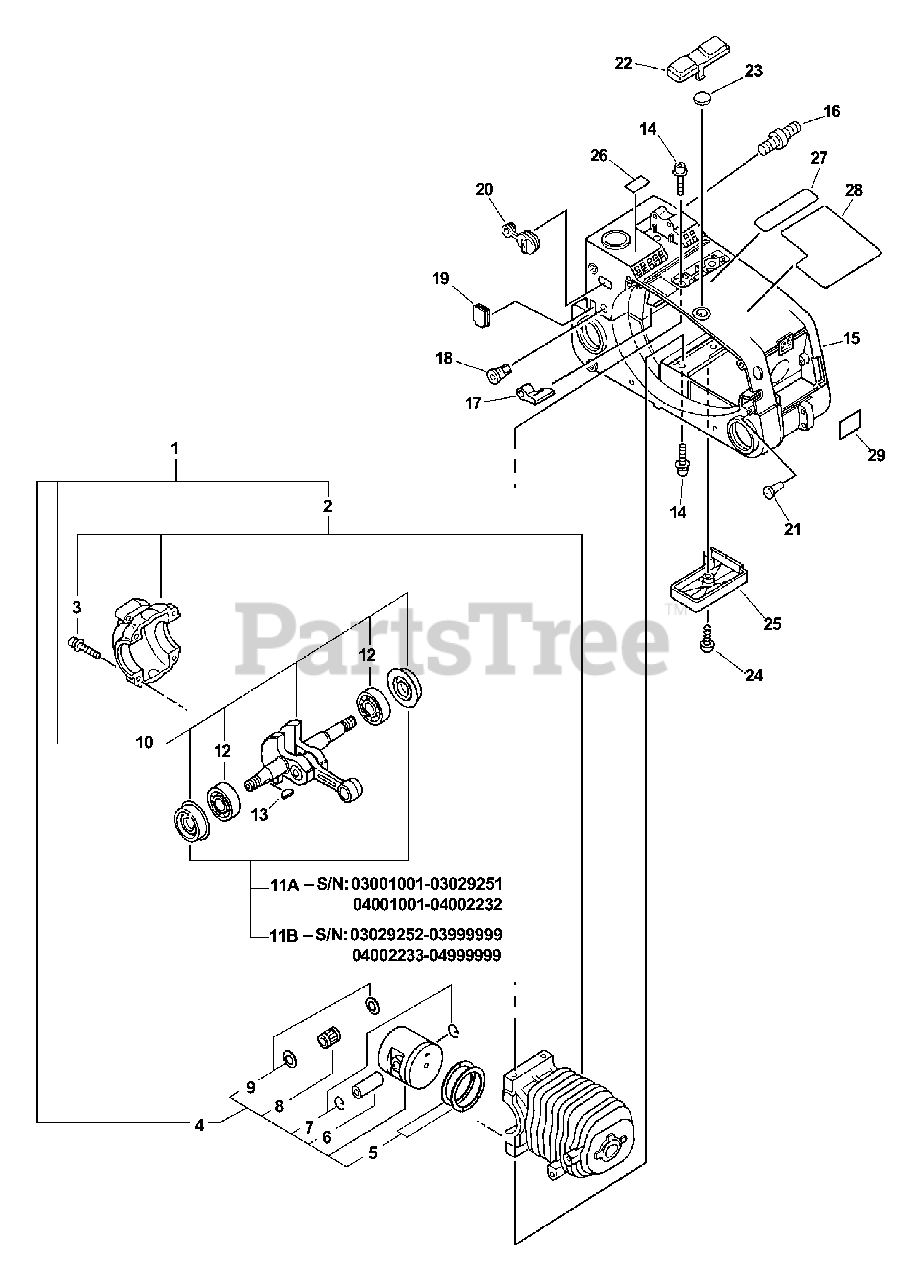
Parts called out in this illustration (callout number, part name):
1	SHORT BLOCK
2	CRANKCASE SET
3	SCREW 5×25
4	PISTON KIT
5	RING, PISTON
6	PIN, PISTON
7	RING, SNAP
8	BEARING, NEEDLE 8
9	WASHER, THRUST
10	CRANKSHAFT ASSY
11A	SEAL, OIL
11B	SEAL, OIL 12
12	BEARING, BALL - 6201 C3
13	KEY, WOODRUFF
14	BOLT 5×16
15	COVER, ENGINE - GRAY
16	BOLT, STUD 6
18	GROMMET, IDLE
20	GROMMET, CHOKE
21	VENT ASSY
24	SCREW 4×16
26	LABEL, PURGE PUMP
27	LABEL, CAUTION
28	LABEL, MODEL
29	LABEL, CAUTION - HOT
